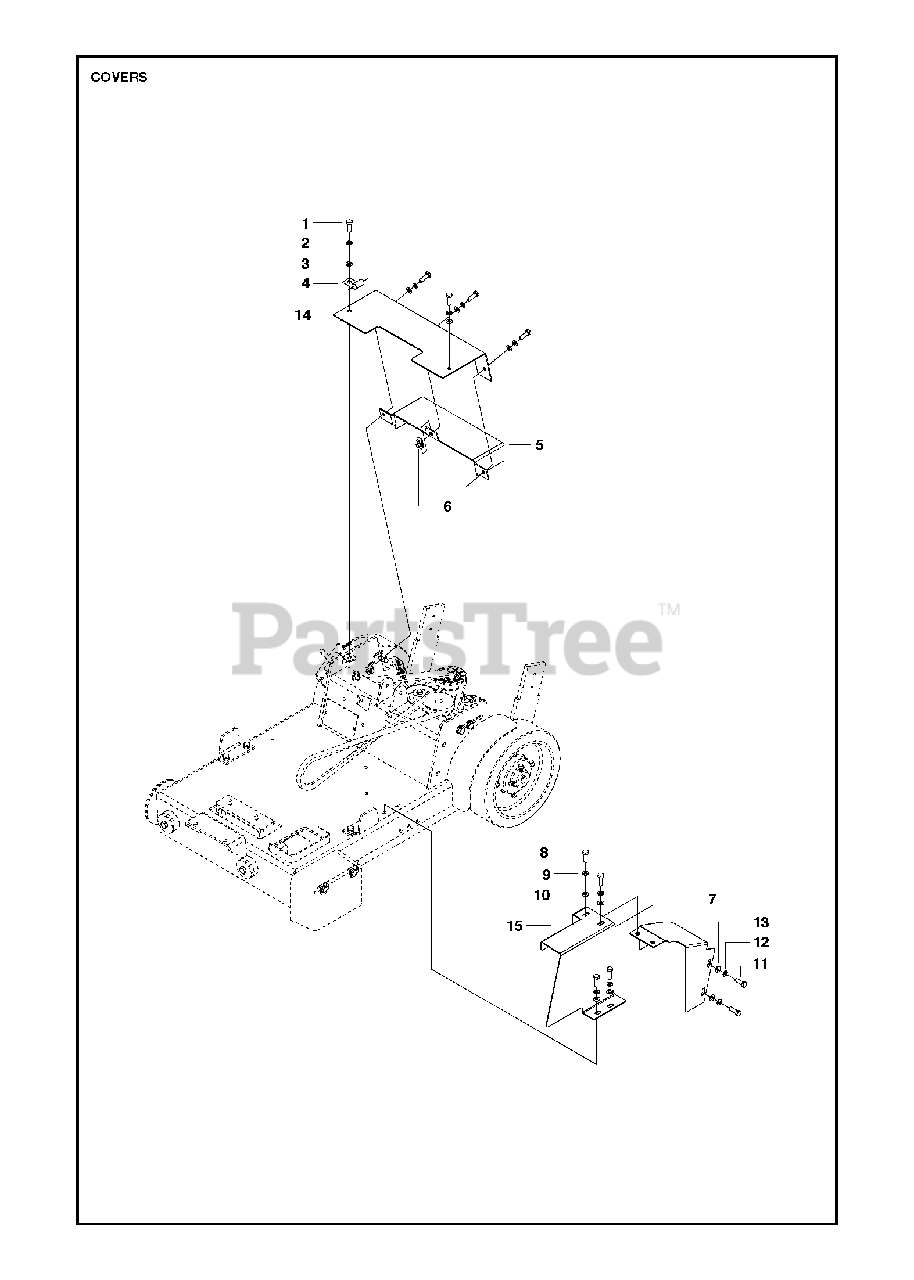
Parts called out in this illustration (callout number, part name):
2	SPRING WASHER
3	WASHER
9	SPRING WASHER
10	WASHER
12	SPRING WASHER
13	WASHER
